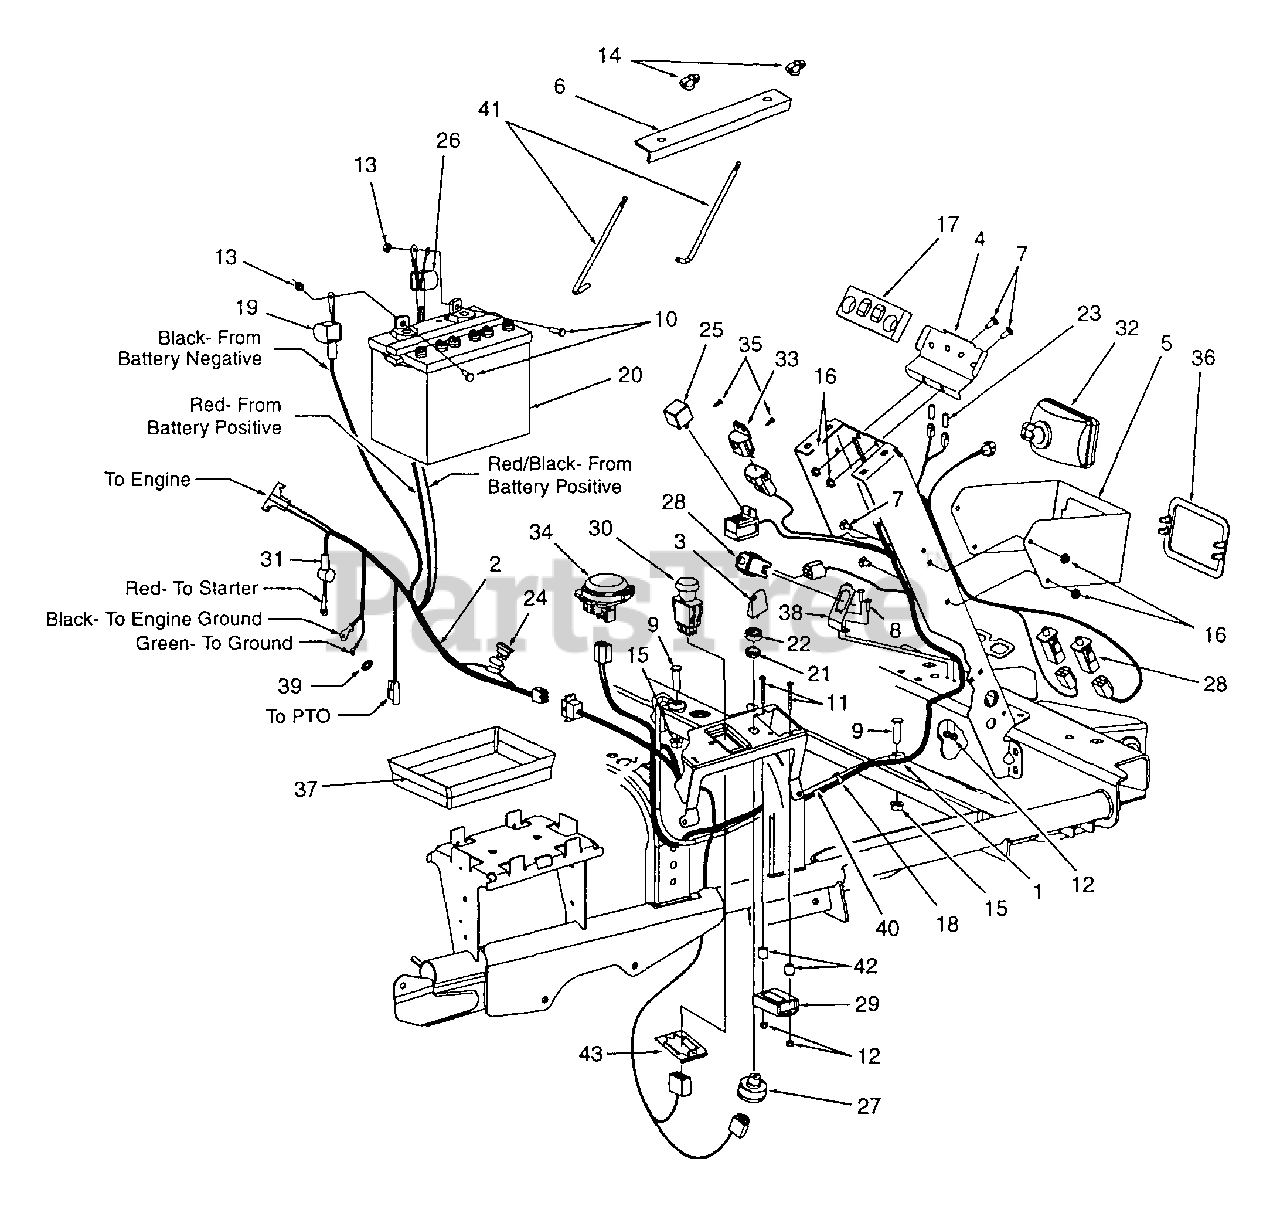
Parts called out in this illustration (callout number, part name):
1	Wire Harness, Main
2	Wire Harness, Engine
3	Key, ignition
7	Bolt, Carriage, 1/4-20 x .62
8	Screw, Machine, #10-24 x 5/8
9	Screw, Hex Cap, 3.8-16 x 1.25
10	Screw, Hex Cap, 1/4-20 x .75 GR5
11	Screw, Pan Hd Cutting, #10-24
12	Nut, Hex Insert Lock, .010-24
13	Nut, Hex Sems, 1/4-20
14	Nut, Nylon Wing, 1/4-20
15	Nut, Hex Flange Lock, 3/8-16
16	Nut, Hex Flange Lock, 1/4-20
17	Foam Protector, Indicator Light
18	Cable Tie
19	Cover, Battery Terminal - Black
21	Nut, Ignition Switch, 5/8-32
22	Cap, Ignition Switch
23	Bulb, Indicator
24	Fuse, Mini, 20Amp
25	Relay
26	Cover, Battery Terminal - Red
27	Switch, Ignition
28	Switch, Plunger Safety
29	Hourmeter/Tachometer
30	Switch, PTO
31	Cover, Terminal - Red
32	Headlight Assembly
33	Sensor, Voltage
34	Switch, Seat
35	Retainer, Ratcheet
36	Bezel, Headlight
37	Tray, Battery
38	Spring, Switch Mounting
39	Washer, External Lock, 5/16
40	Rod, Harness Mtg
41	Rod, Battery Retainer
42	Spacer, .315 x .50 x .52
43	Bracket, PTO Switch Retainer
